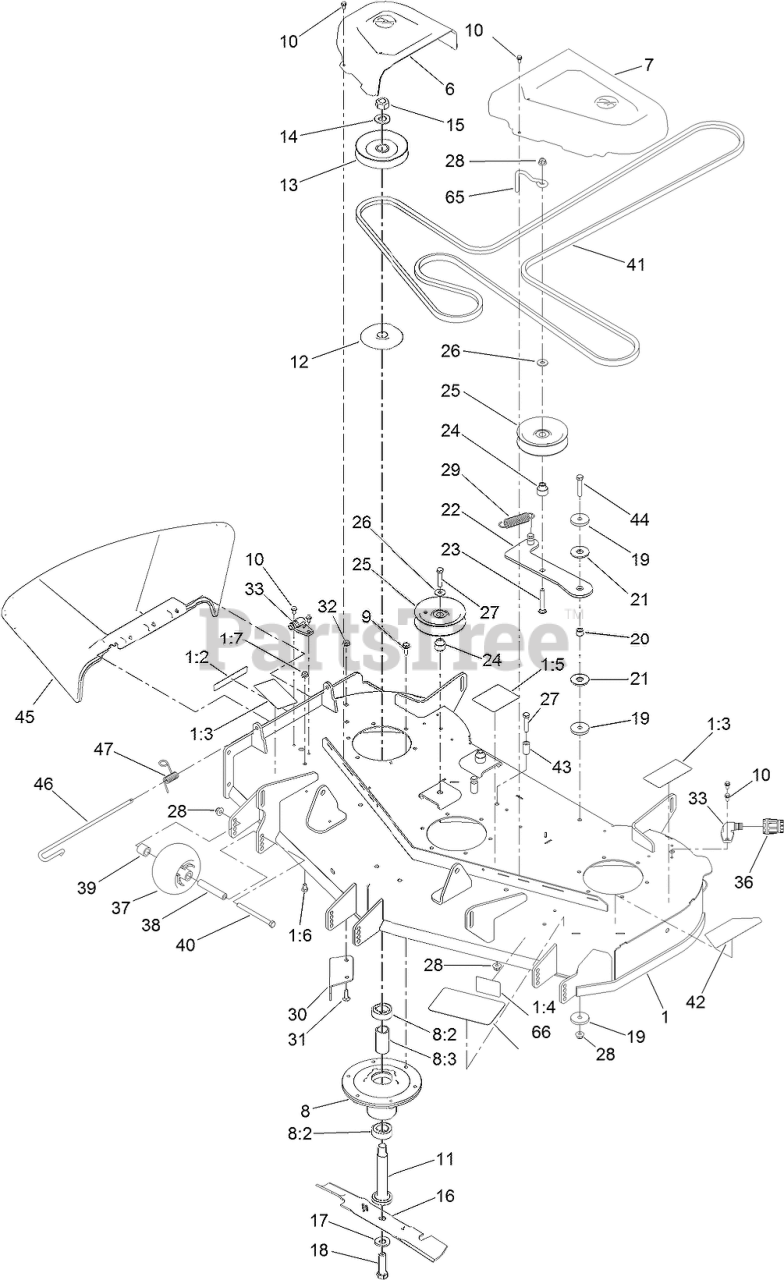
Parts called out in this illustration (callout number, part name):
1	DECK ASM
1:2	DECAL-DANGER
1:3	DECAL-DANGER, DECK
1:4	DECAL-SCALP, ANTI
1:5	DECAL-ROUTING, BELT
1:6	SCREW-HH
1:7	NUT-HF, NI
6	COVER-BELT, RH
7	COVER-BELT, LH
8	SPINDLE ASM
8:2	BEARING-BALL
8:3	SPACER-BEARING
9	SCREW-TAPTITE
10	SCREW-HWH
11	SHAFT-SPINDLE
12	SHIELD-BEARING
13	PULLEY
14	WASHER
15	NUT-HEX
16	BLADE-HI FLO, 16.50 INCH
17	WASHER-BELLEVILLE
18	SCREW-BLADE
19	WASHER-PLAIN
20	BUSHING-LEVER, LIFT
21	WASHER-FRICTION, COMPOSITE
22	ARM-IDLER
23	SCREW-CARR
24	BUSHING-IDLER
25	PULLEY-IDLER, FLAT
26	WASHER-HARDENED
27	SCREW-HH
28	NUT-HF, NI
29	SPRING-EXTENSION
30	BAFFLE-CUTOFF
31	SCREW-CARR
32	NUT-HF, NI
33	FITTING-WASHOUT
36	CONNECTOR-HOSE
37	ROLLER-SCALP, ANTI
38	TUBE-SPANNER
39	SPACER-AXLE, REAR
40	SCREW-HH
41	V-BELT
42	DECAL-DECK
43	SPACER
44	SCREW-HH
45	DEFLECTOR-DISCHARGE
46	PIN-CHUTE
47	SPRING-TORSION
65	BELT GUIDE - IDLER
66	TREAD-STEP
